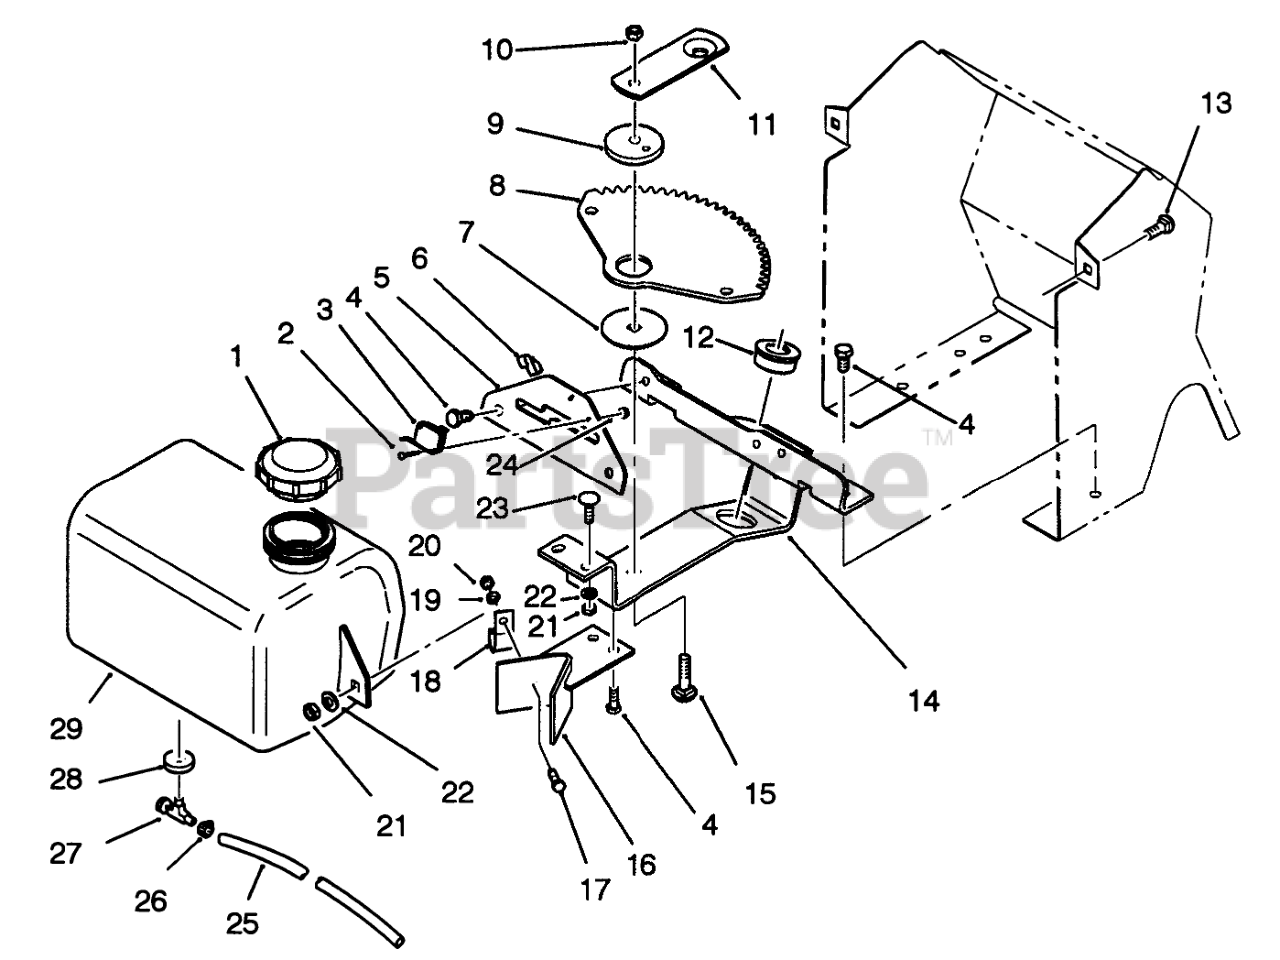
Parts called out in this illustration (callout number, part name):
1	CAP GAS
2	Screw
3	SWITCH - CLUTCH
4	HEX WASH HD SCREW
5	PLATE-SHIFT R
6	CLIP-CABLE
7	WASHER-BEARING
8	GEAR-SECTOR
9	BUSHING
11	Plate
12	BEARING-WHEEL
13	SCREW-CARR
14	STEERING BRKT - W/A R
15	SCREW-CARR
16	Stop
17	Bolt
18	CLIP
20	NUT-LOCK, NI
21	NUT-LOCK, NI
22	WASHER-PLAIN
23	Bolt-Carriage
24	NUT HEX 4-40 ELAST
25	FUEL HOSE(1 FT.6554)
26	CLAMP-HOSE
27	VALVE-FUEL
28	BUSHING
29	Tank-Fuel (Incl. Ref. #27-29)
